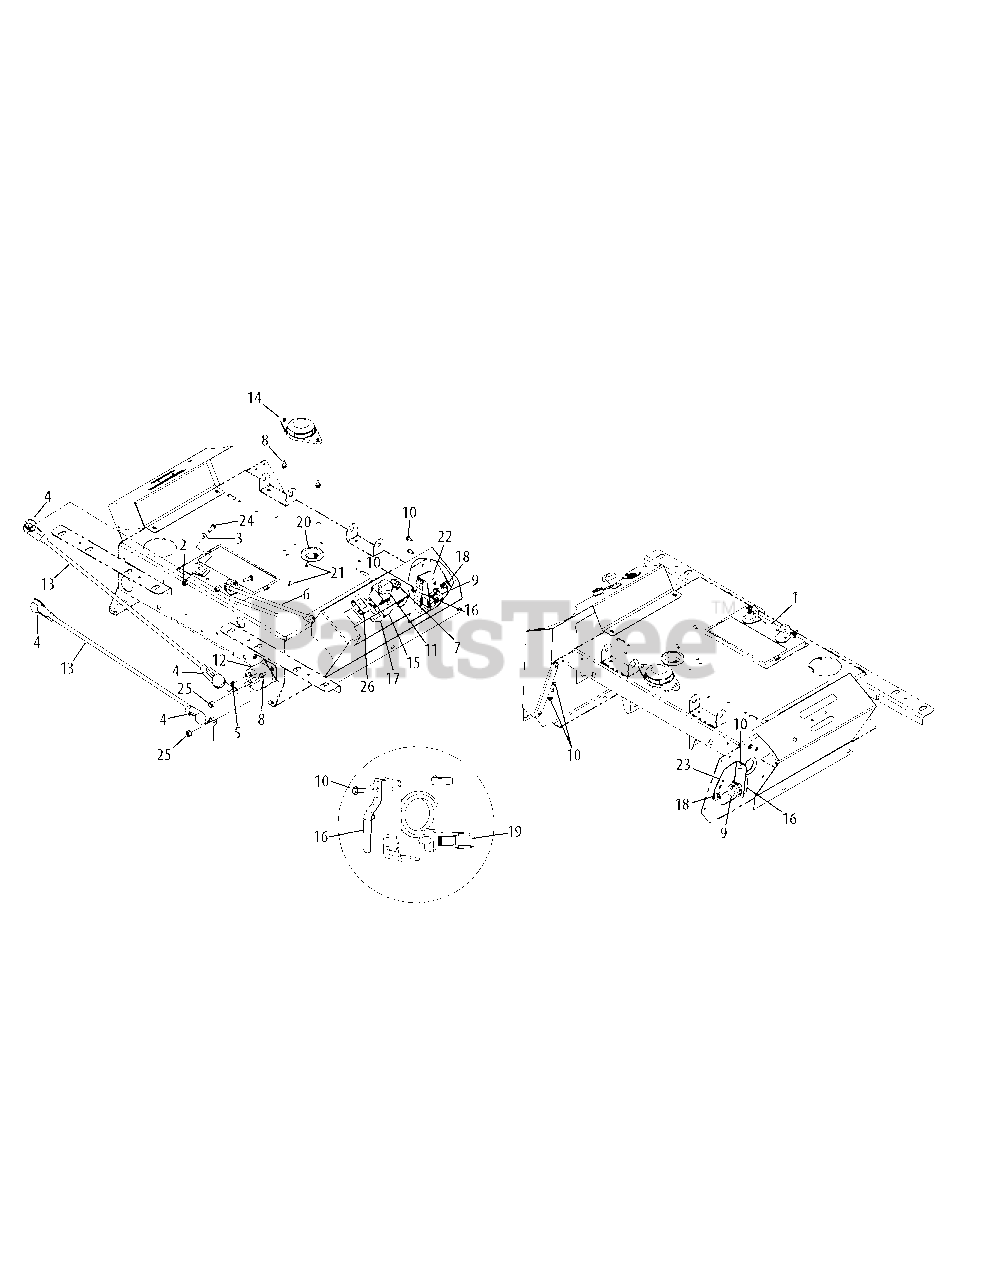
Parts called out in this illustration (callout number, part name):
1	Battery
2	Nylock Nut, 1/4-20
3	Washer, .281 x .625 x .063
4	Boot Terminal, 1.00 x 2.50
5	Nylock Nut, #10-32
6	Battery Cable
7	Nut, 5/8-32
8	Hex Flange Screw, 1/4-20 x .500
9	Switch
10	Flange Screw, #10-24 x .500
11	PTO Switch
12	Solenoid
13	Battery Cable
14	Seat Switch
15	Ignition Switch
16	Renovator Spring
17	PTO Bracket
18	Nut, #10-24
19	Delta Switch
20	Grommet, 1/8 x 1.5 x 2.13
21	Electric CDT Clip
22	RH Deck Switch Mount Bracket
23	LH Deck Switch Mount Bracket
24	Hex Screw, 1/4-20 x .75
25	Hex Lock Nut, 5/16-18
26	Hour Meter
